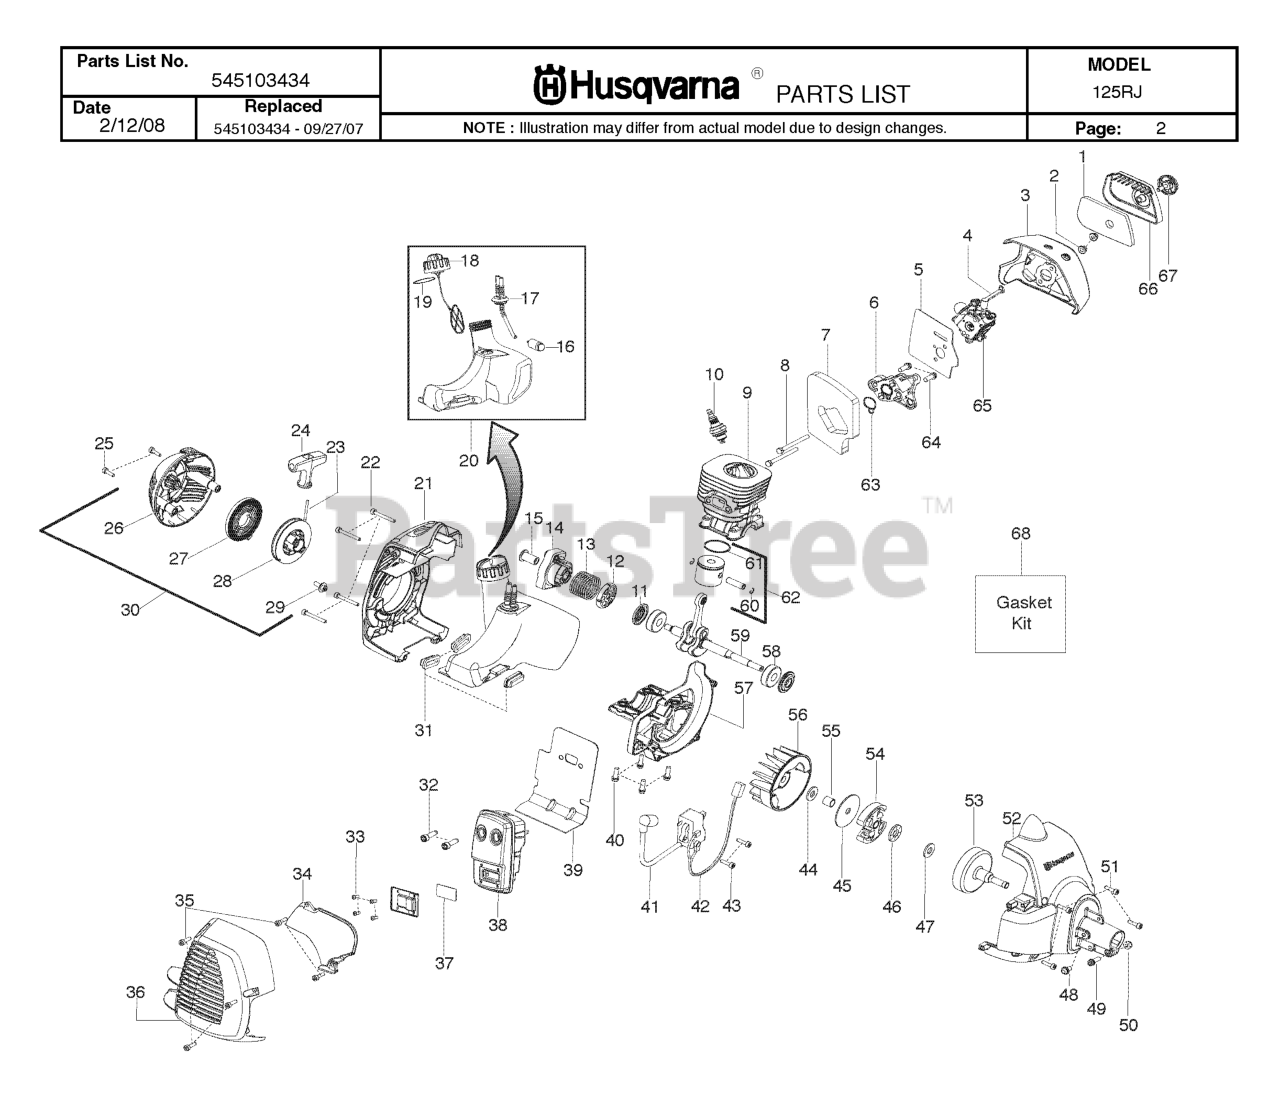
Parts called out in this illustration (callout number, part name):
1	FILTER AIRBOX
3	RP_AIR BOX
4	CHOKE LEVER
5	KIT GASKET CARB
6	CARB ADAPTOR
7	KIT GASKET 28CC TRIMMER
8	BOLT CARB ADAPTOR
9	CYLINDER
10	Plug - Spark (RCJ-8Y)
11	KIT SEAL CRANKSHAFT
12	WASHER STARTER
13	SPRING STARTER CUP
14	ASSY-STARTER CUP
15	COUPLING STARTER
16	FUEL PICK-UP ASSY
17	KIT FUEL LINE
18	ASSY-CAP W/RETAINER
19	O RING NITRILE
20	ASSY FUEL TANK HVA
21	REAR SHROUD
24	STARTER HANDLE GRAY
25	SCREW M5-0.8X30MM
26	STARTER HOUSING
27	%KIT STARTER SPRING
28	KIT STARTER PULLEY
30	ASSY-STARTER HSG.
31	ISOLATOR FUEL TANK
32	BOLT MUFFLER
33	SCREW-10-16 X 1/2 HI-LO
34	SHIELD HEAT
35	SCREW M4 X 1.75 PT 16MM
36	GUARD-MUFFLER
37	KIT SPARK ARRESTOR SCREEN
38	ASSY-MUFFLER
39	GASKET PAPER METAL
40	SCREW-M5-0.8 X 25MM(TAP)
41	IGNITION MODULE MBU-7
42	ASSY MODULE LEAD WIRE
43	SCREW M4 X .70 TT 16MM
44	WASHER CLUTCH
45	WASHER-CLUTCH
46	BEARING THRUST
47	WASHER THRUST
50	LOCKNUT-HEX 10-24
51	SCREW M4 X .70 TT 16MM
52	FAN HSG ASSY
53	ASSY-CLUTCH DRUM
54	%KIT CLUTCH ASSY
55	SPACER FLYWHEEL
57	CRANKCASE CASTING
58	BEARING RADIAL BALL (6201)
59	KIT CRANKSHAFT ASSY
60	WRIST PIN RET.
61	RING PISTON
62	KIT PISTON 28CC TRIMMER
63	KIT GASKET 28CC TRIMMER
64	SCREW-M5-0.8 X 25MM(TAP)
65	CARBURETOR KIT W41
66	COVER-AIR BOX
67	KNOB ASSY AIRBOX COVER
68	KIT GASKET 28CC TRIMMER
